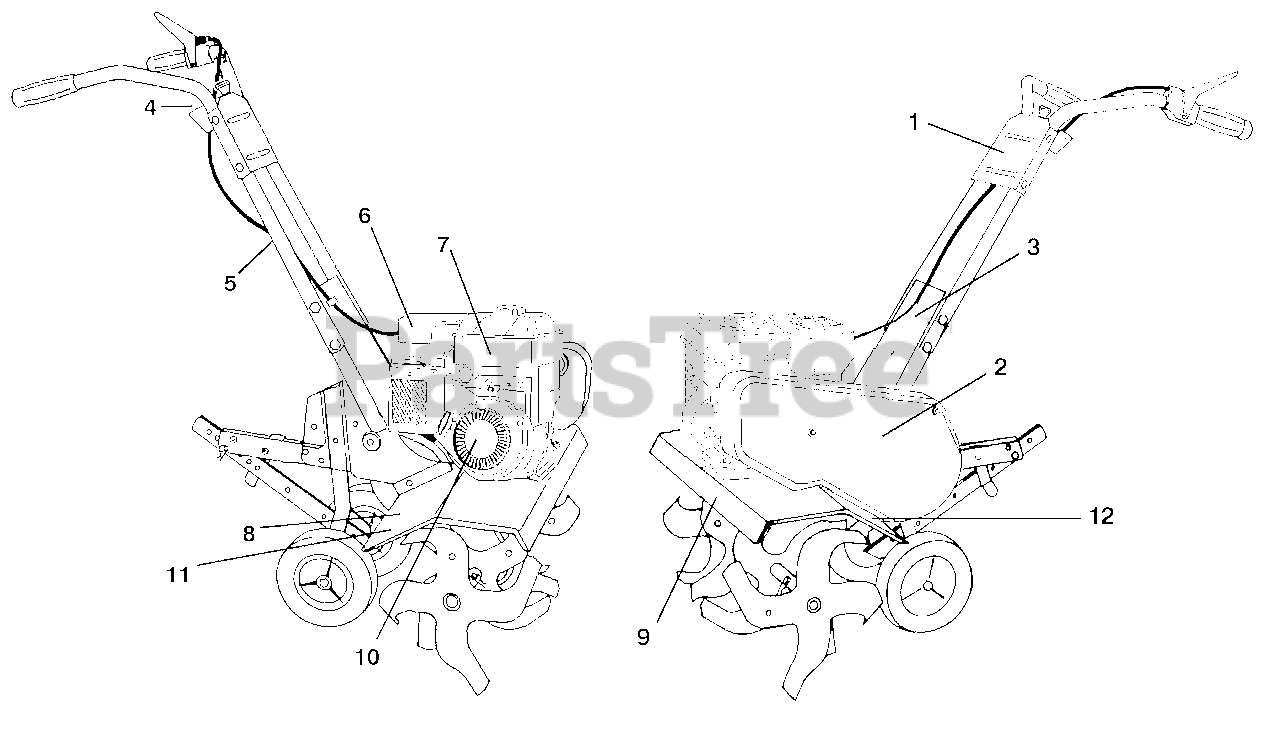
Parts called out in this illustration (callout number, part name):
1	Decal, Poulan Pro
2	Decal, Poulan Pro, 800 Series/26"
3	Decal, Forward and Reverse
4	Decal, Reverse, Tine Control
5	Decal, Hand Placement
6	Decal, Engine
7	Decal, OHV, I/C
8	Decal, Warning
9	Decal, Heavy Duty
10	Decal, Rewind Starter
11	Decal, Warning, Rotating Tines
12	Decal, Compliance
12	Manual, Operator's, English/French
12	Manual, Repair Parts
